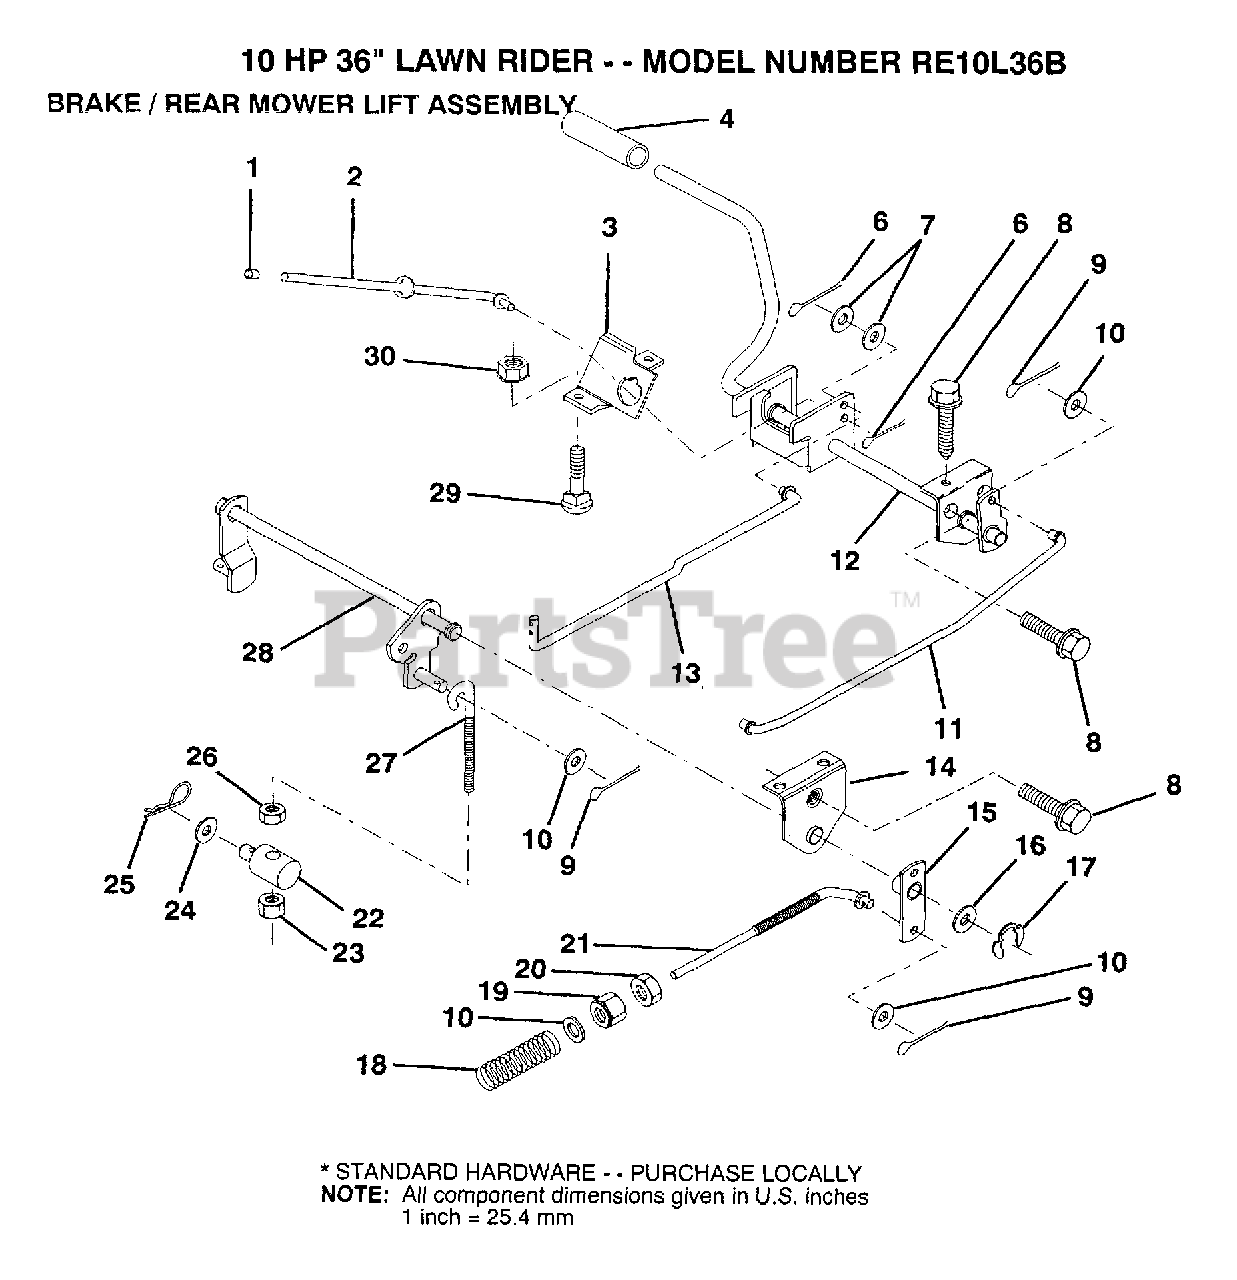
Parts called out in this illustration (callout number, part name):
1	PLUNGER CAP T
2	"ROD,PARK BRAKE"
3	"BRKT,PARK BRAKE"
4	FOOT PEDAL COVER
7	WASHER
8	SCREW LT
9	COTTER PIN
10	WASHER
13	"ROD,CLUTCH"
14	"BRKT,LIFT SHAFT"
15	PVT BRAKE ARM ASM
16	WASHER T
17	KLIP RING
18	SPRING ROD LT
19	NUT
20	NUT
24	WASHER
25	SPRING.RETAINER
26	LOCKNUT
27	"LINK, MOWER REAR"
